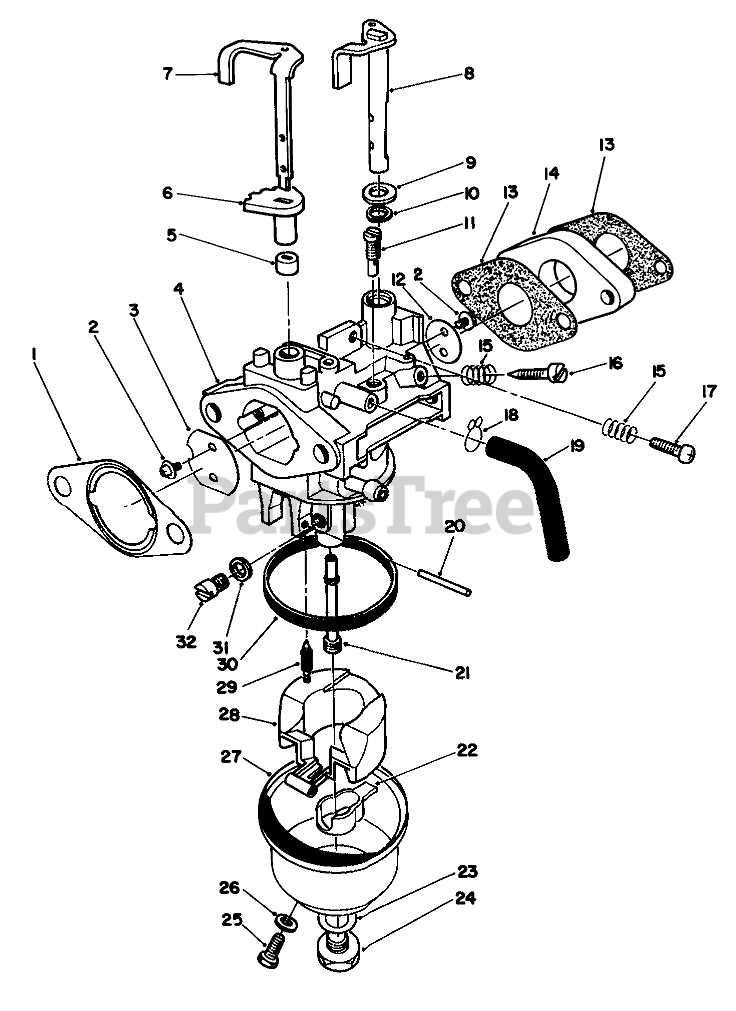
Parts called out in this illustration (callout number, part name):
1	GASKET F/W ENGINE
2	Screw
3	VALVE
4	Body-Carburetor
5	LOWER CHOKE RING
6	UPPER CHOKE RING
7	SHAFT
8	SHAFT
9	WASHER
10	Seal-Throttle Shaft
11	JET - PILOT
12	VALVE
13	GASKET INTAKE
14	INSULATOR - CARB.
15	SPRING-PILOT SCREW
16	ADJUSTER
17	SCREW
18	CLAMP
20	Pin
21	NOZZLE - MAIN
22	SPACER
23	GASKET
24	SCREW
25	SCREW
26	GASKET
28	FLOAT
29	NEEDLE
30	FLOAT BOWL GASKET
31	SPACER
32	JET - MAIN
